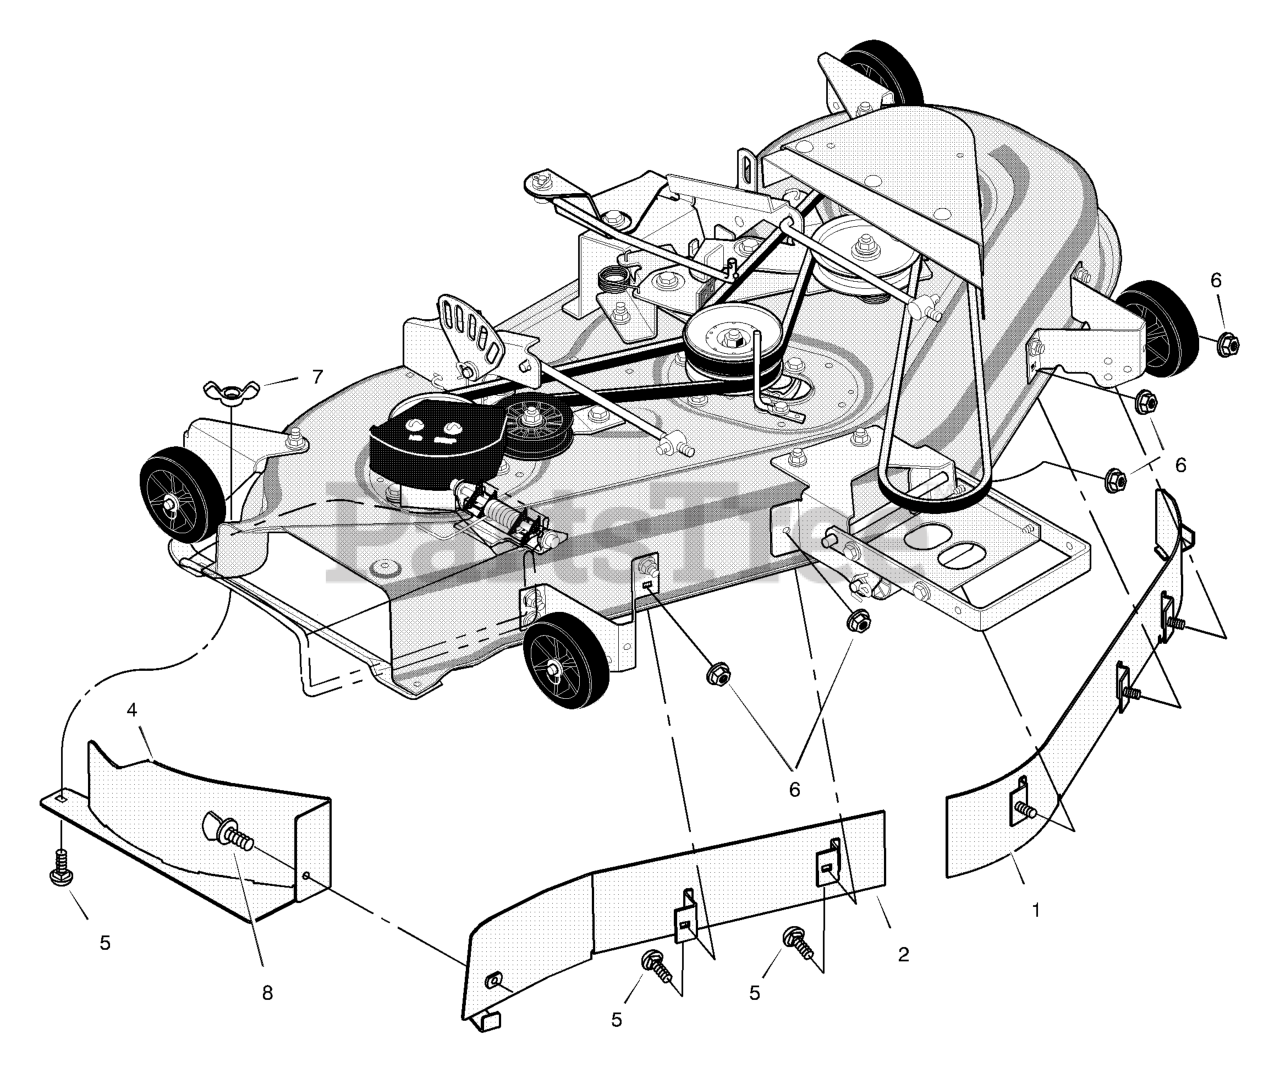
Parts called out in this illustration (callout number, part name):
1	Baffle, Left-Front
2	Baffle, Right-Front
4	Plate, Mulcher
5	Bolt, Carriage
6	Nut, Flange
7	Wingnut
8	Screw, Thumb
